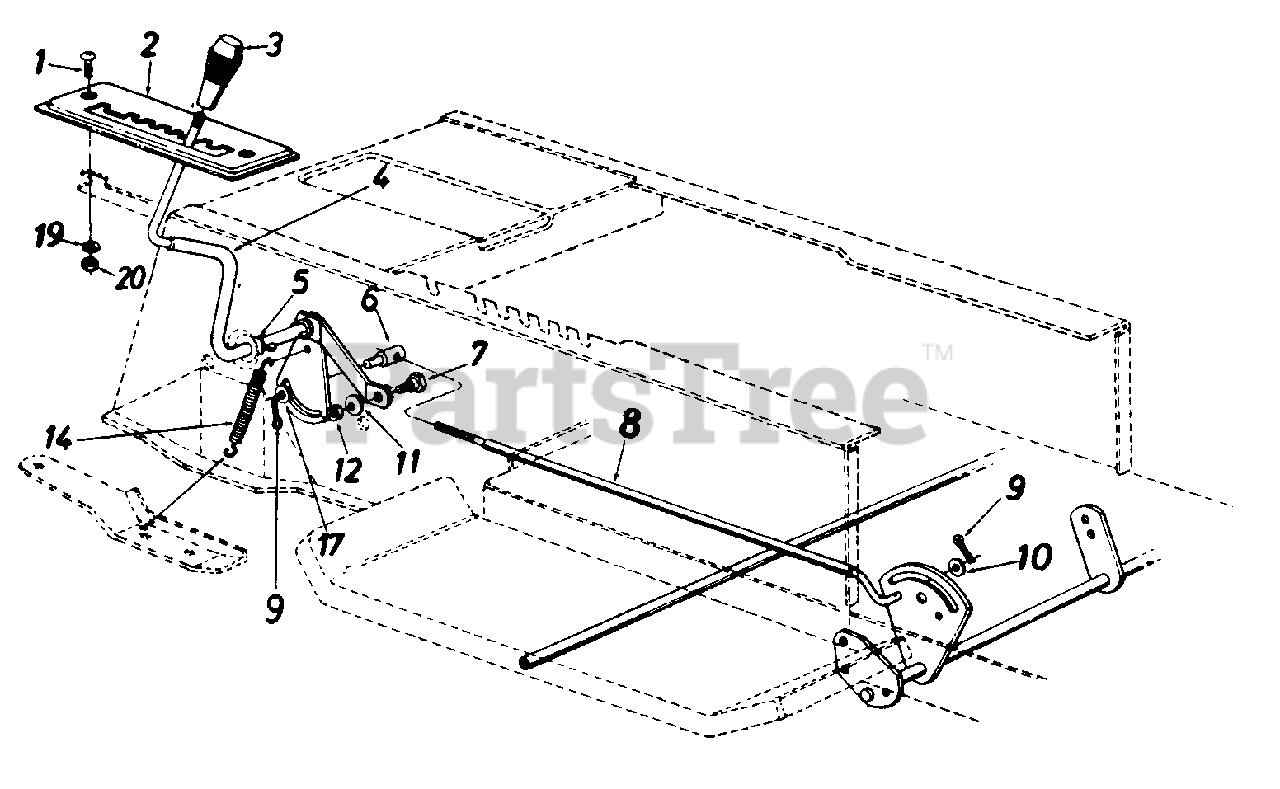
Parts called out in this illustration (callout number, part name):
1	Truss Mach. Scr. 1/4-20 x .75" Lg
4	Speed Selector Cam Ass'y.
5	Flat Washer .53" I.D. x .93"
6	Ferrule 3/8-24 x .37" Dia.
7	Shoulder Bolt
8	Speed Control Link
9	Cotter Pin 3/32" Dia. x 1.0
10	Fl-Wash. .469" I.D. x .88"
11	L-Wash. 5/16" I.D.
12	Hex Nut 5/16-18 Thd.
14	Spring .38" O.D. x 3.18" Lg.
17	Fl-Wash. .385" I.D. x .62"
19	L-Wash. 1/4" I.D.
20	Hex Nut 1/4-20 Thd.
